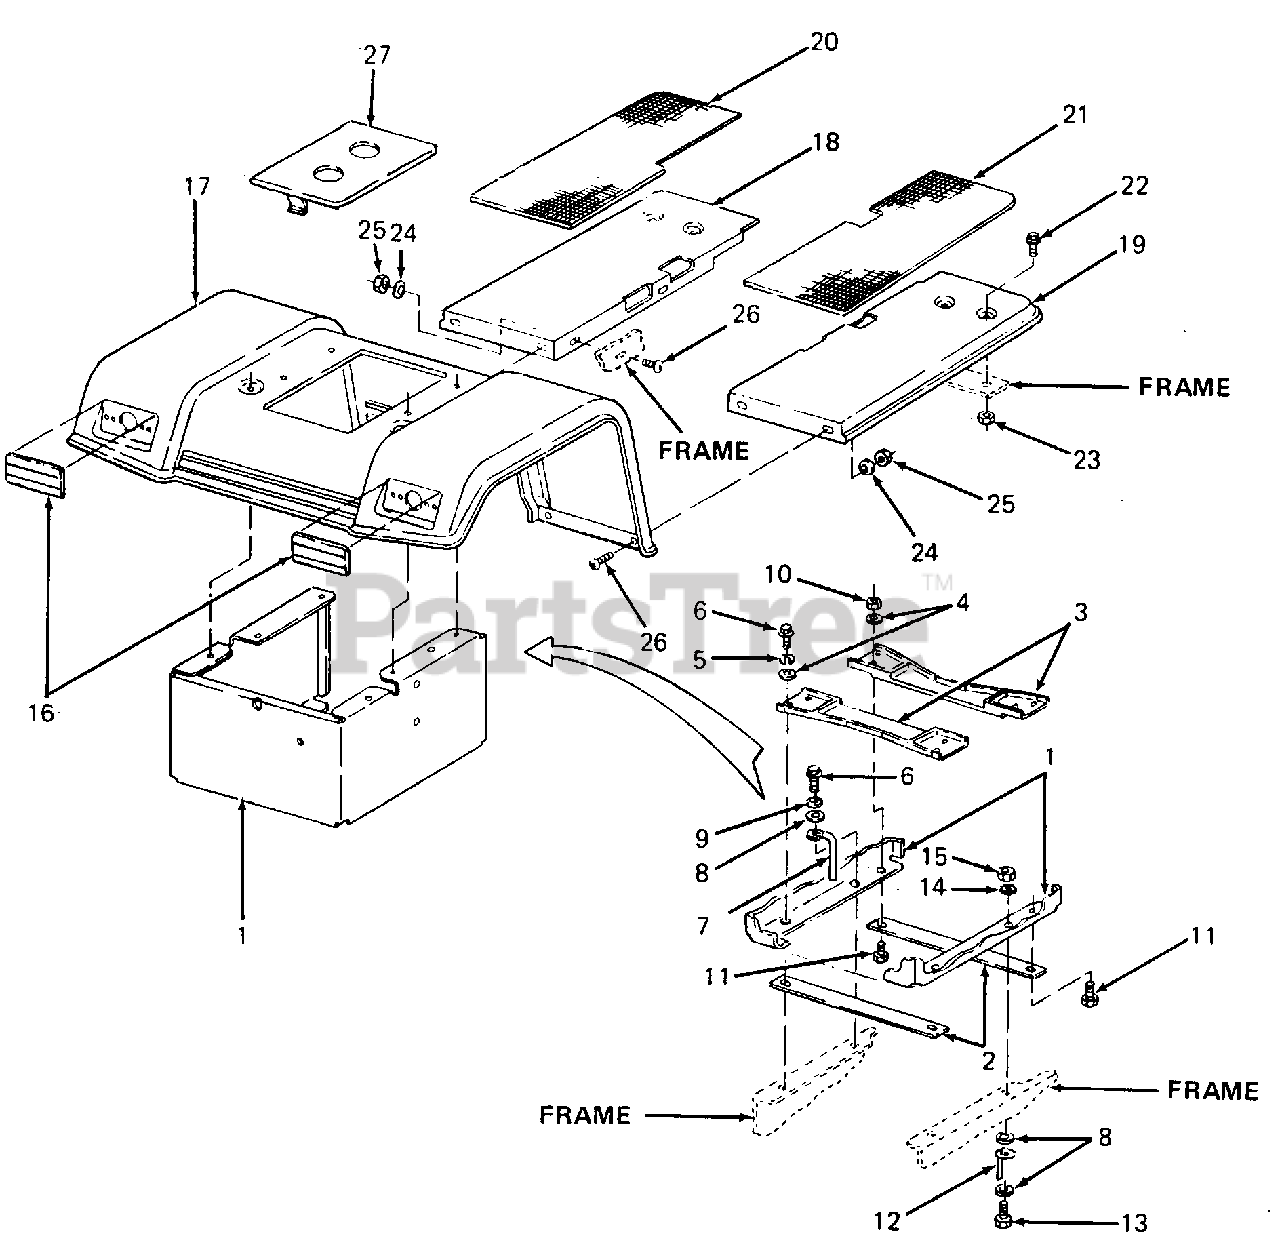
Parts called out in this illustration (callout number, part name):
1	Box, Fender Mounting
2	Plate, Reinforcement
3	Tray, Battery
4	Washer, Flat, .344 X .875 X .06 Thk
5	Washer, Lock, 5/16
6	Screw, Hex Wash Hd Tapp, 5/16-18 X .88 Lg
7	Rod, Belt Guide
8	Washer, Flat, .344 X 1.12 X .12 Thk
9	Washer, Bell, .345 X .88 X .06 Thk
10	Nut, Hex Patch Lock, 5/16-18
11	Screw, Hex Cap, 5/16-18 X .75 Lg GR5
12	Guide, Transmission Belt
13	Screw, Hex Cap, 5/16-18 X 1.0 Lg GR5
14	Washer, Int Ext Lock, 5/16 X 7/8
15	Nut, Hex, 5/16-18 GR5
16	Reflector
21	Pad, RH - Foot Rest
22	Screw, Hex Wash Hd Tapp, 5/16-18 X .62 Lg
23	Nut, Hex Center Lock, 5/16-18 GR5
24	Washer, Bell, .265 X .75 X .062 Thk
25	Nut, Hex, 1/4-20
26	Screw, Truss Mach, 1/4-20 X .50 Lg
27	Cover, Battery
